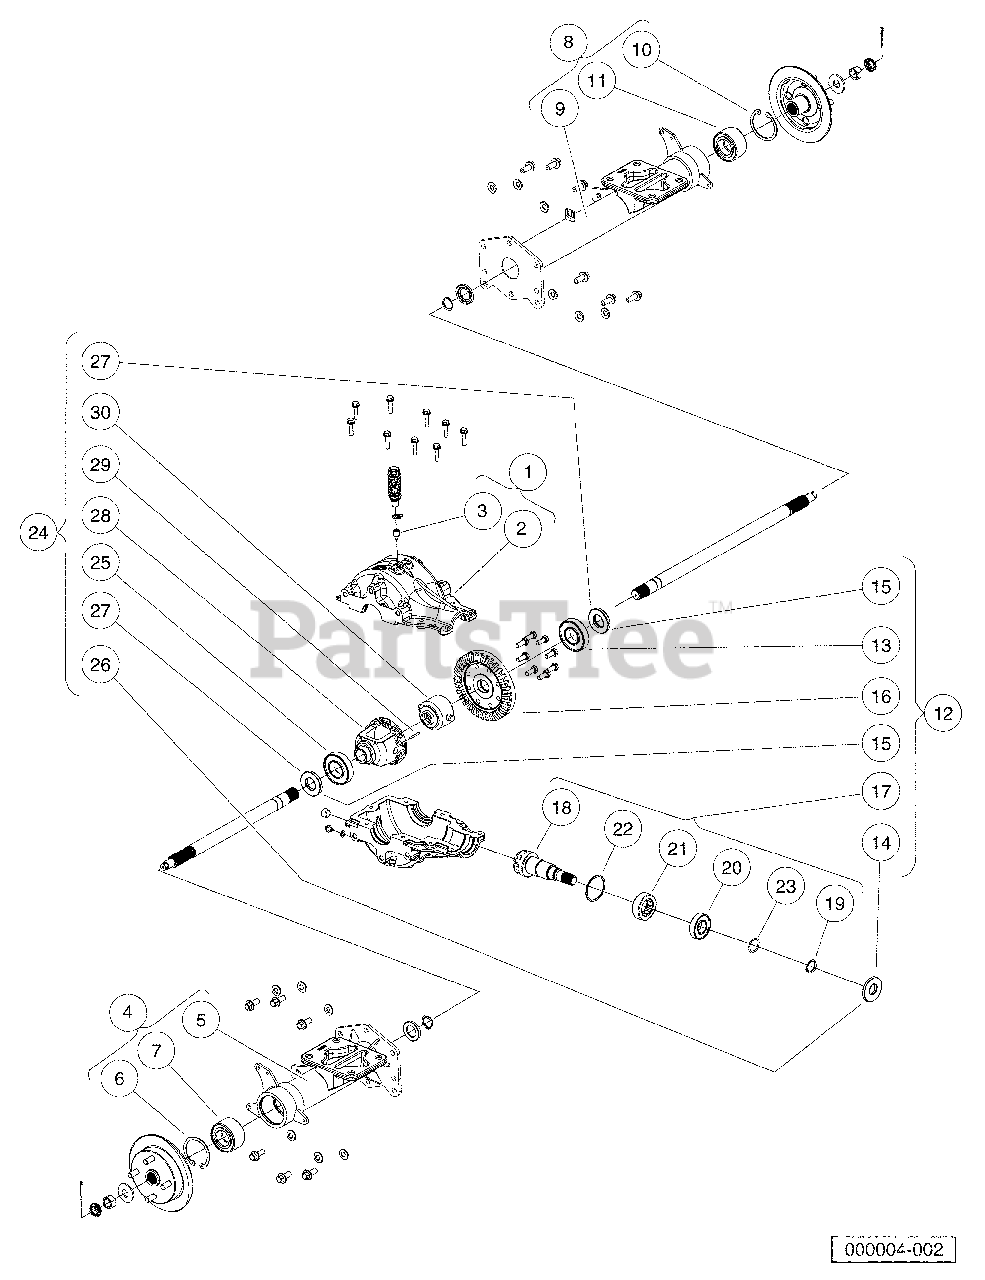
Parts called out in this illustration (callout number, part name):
1	Asm, Gearcase, Upper
2	Gearcase, Upper, Machined
3	Vent, Top, Upper Housing
4	Asm, Axle Tube, RH
5	Weldment, Axle Tube Rh
6	Ring, Retaining, Internal
8	Asm, Axle Tube, LH
9	Weldment, Axle Tube Lh
10	Ring, Retaining, Internal
12	Kit, Rear Axle Gear Repair
13	Bearing, Ball
14	Seal, Dual-Lip 25x 62x 7tc
15	Seal, Dual-Lip 30x 62x 8tc
17	Asm, Pinion W/ Bearings
18	Pinion, I0t Machined
19	Ring, Retaining, External
20	Bearing, Ball
21	Bearing, Needle, Drawn Shell
22	Washer, 2.625 X 2.367 X .06
23	Shim, 1.50 X 1.189 X .008
24	Asm, Differential & Carrier
25	Bearing, Ball
26	Seal, Dual-Lip 25x 62x 7tc
27	Seal, Dual-Lip 30x 62x 8tc
28	Housing, Differential, Mach
29	Pin, Dowel, 4 X 35
30	Asm, Locker, Nongrease/Spacers
